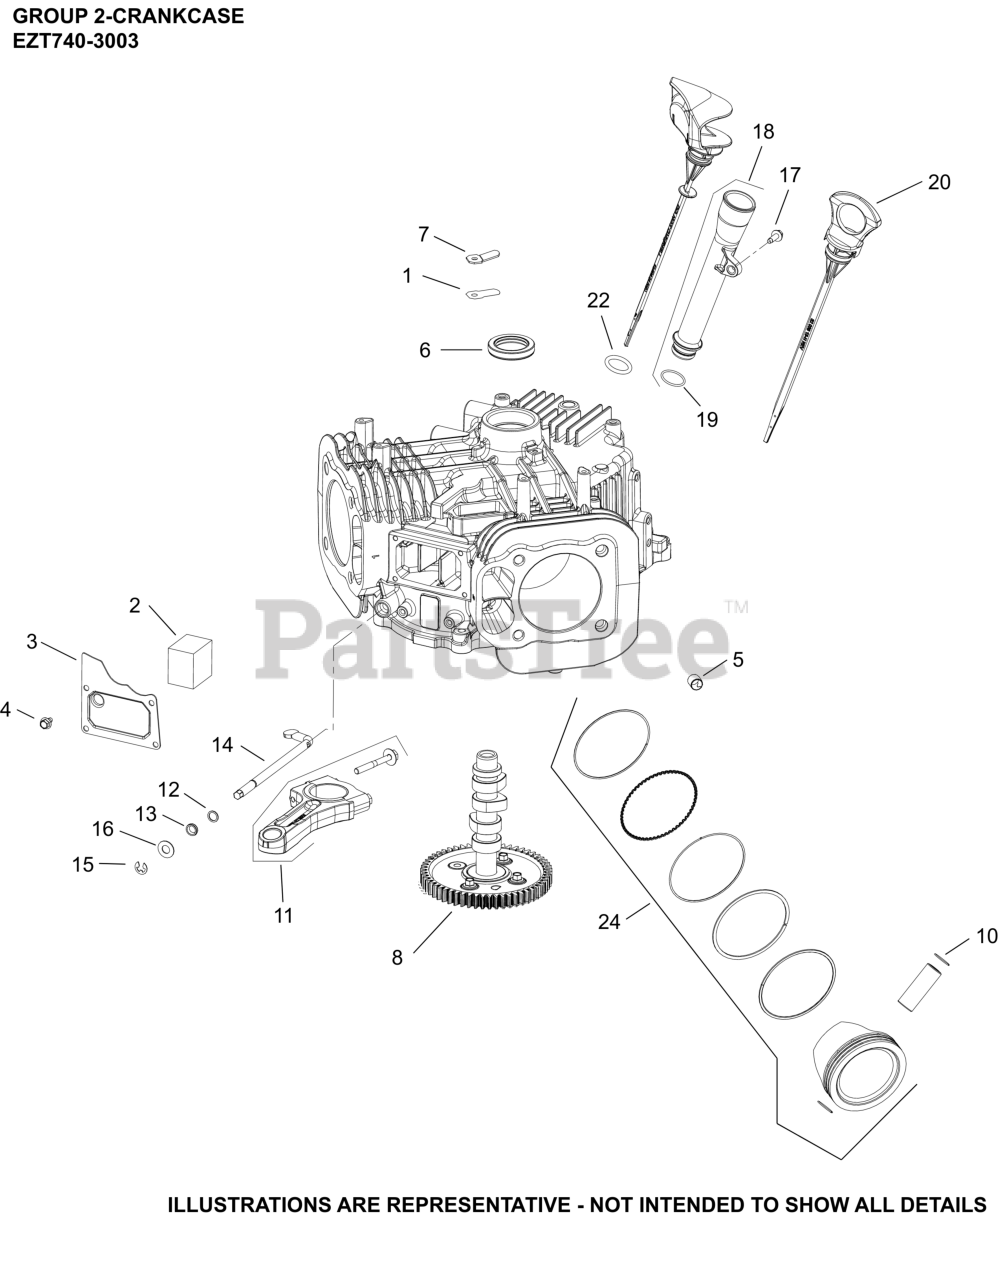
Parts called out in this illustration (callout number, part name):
1	REED, BREATHER
2	FILTER, BREATHER
3	COVER, BREATHER MEDIA
4	SCREW, THREAD FORMING
5	PIN, LOCATING
6	SEAL, OIL (HELIX LIP)
7	RETAINER, REED
8	CAMSHAFT ASSY
10	RETAINER, PISTON PIN
11	ROD, ASSEMBLY CONNECTING
12	WASHER, FLAT 11/32"
13	SEAL, GOVERNOR CROSS SHAFT
14	KIT, CROSS SHAFT
15	CLIP, RETAINER GOVERNOR SHAFT
16	WASHER, FLAT 9 MM
17	SCREW, THREAD FORMING
18	TUBE ASSEMBLY, OIL FILL
20	DIPSTICK, ASSY
24	KIT,PSTN/RNG STYLE B(STD)
